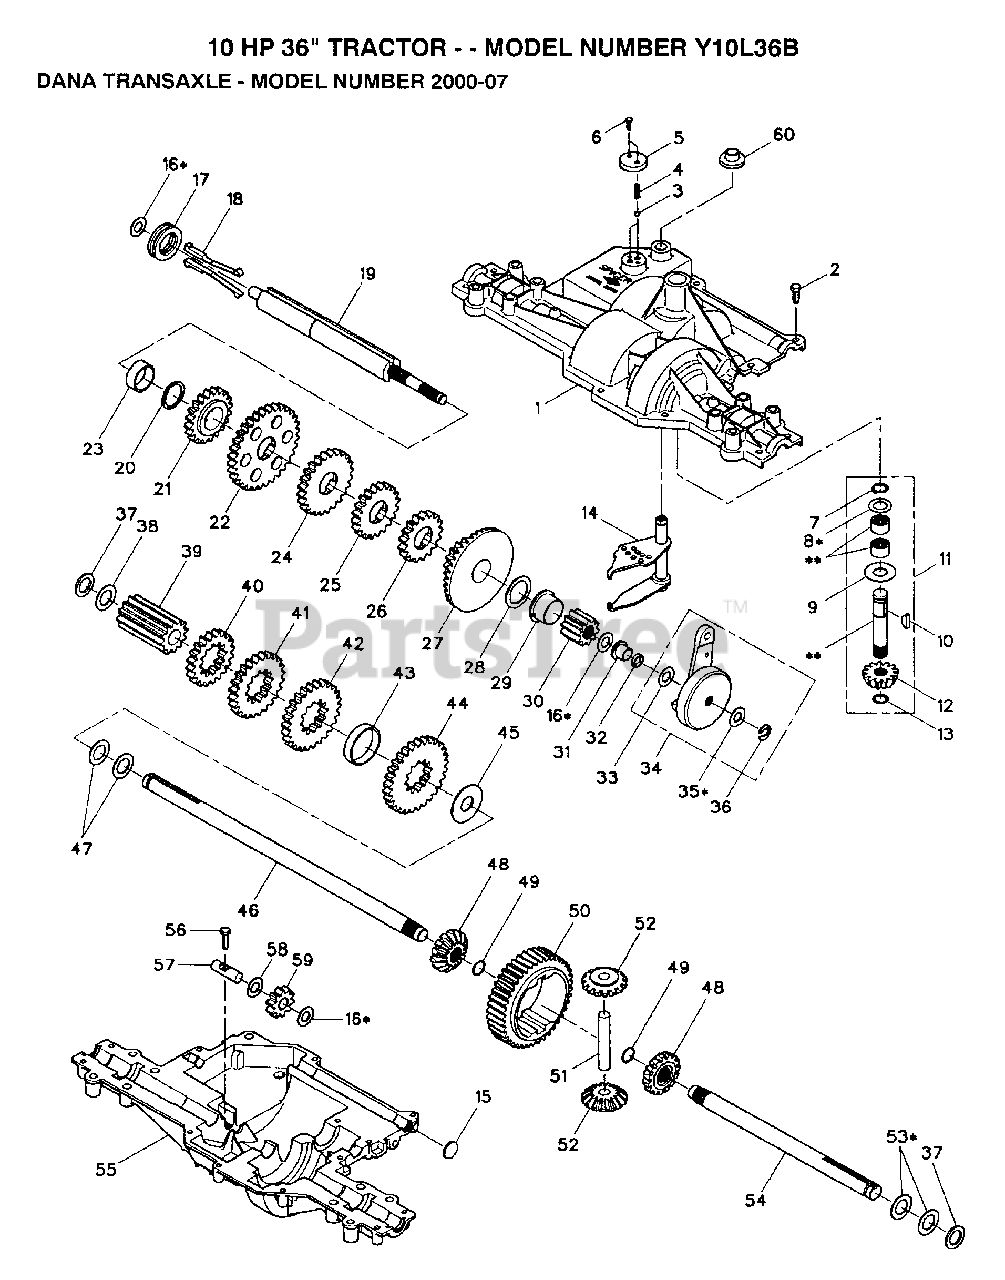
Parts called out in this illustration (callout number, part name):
1	HOUSING. UPPER
4	SPRING, DETENT
5	COVER, DETENT
6	SCREW, TAPPING, LARGE #8-32 X .50
7	RETAINING RING LT
8	ASM KIT SHIM 4689
9	WASHER T
10	WOODRUFF KEY
11	ASSEMBLY, KIT, INPUT SHAFT
12	PINION,, BEVE, 13 TEETH
13	RING, RETAINING
14	ASSEMBLY, SHIFTER
16	ASSEMBLY, KIT, SHIM, .500 SHAFT
18	ASSEMBLY, KIT, CLUTCH KEYS
19	SHAFT, DRIVE
20	"RING,RETAINING LT"
21	GEAR, SPUR, 20 TEETH
22	GEAR , SPUR, 32 TEETH
23	SPACER 1.130X1.330X.465
24	GEEAR, SPUR, 24 TEETH
25	GEAR, SPUR, 20 TEETH
26	GEAR, SPUR, 17 TEETH
27	GEAR BEVEL 39 & SPUR 15
28	WASHER, PLAIN 1,135 X 1.56 X .062
29	BEARING, FLANGE
30	GEAR, SPUR, 10 TEETH
31	BEARING, FLANGE
33	WASHER T
34	ASSEMBLY, KIT CONE BRAKE
35	ASSEMBLY, KIT, SHAM .464 SHAFT
37	NEOPRENE WASHER
38	WASHER 062
39	GEAR, SPUR, 12 TEETH
40	GEAR, SPUR, 17 TEETH
41	GEAR, SPUR, 24 TEETH
42	GEAR, SPUR, 26 TEETH
43	SPACER 1.710X1.910X.375
44	GEAR SPUR, 29 TEETH
45	WASHER, PLAIN, .758 X 1.88 X .062
47	WASHER 031
48	GEAR 15T T
49	"RING,RETAINING LT"
50	GEAR, SPUR, 41 TEETH
51	SHAFT T
52	GEAR 1ST T
53	ASM KIT SHIM
55	HOUSING, LOWER
57	SHAFT, IDLER
58	WASHER T
59	GEAR, SPUR, 10 TEETH
60	SHIFTER BOOT
